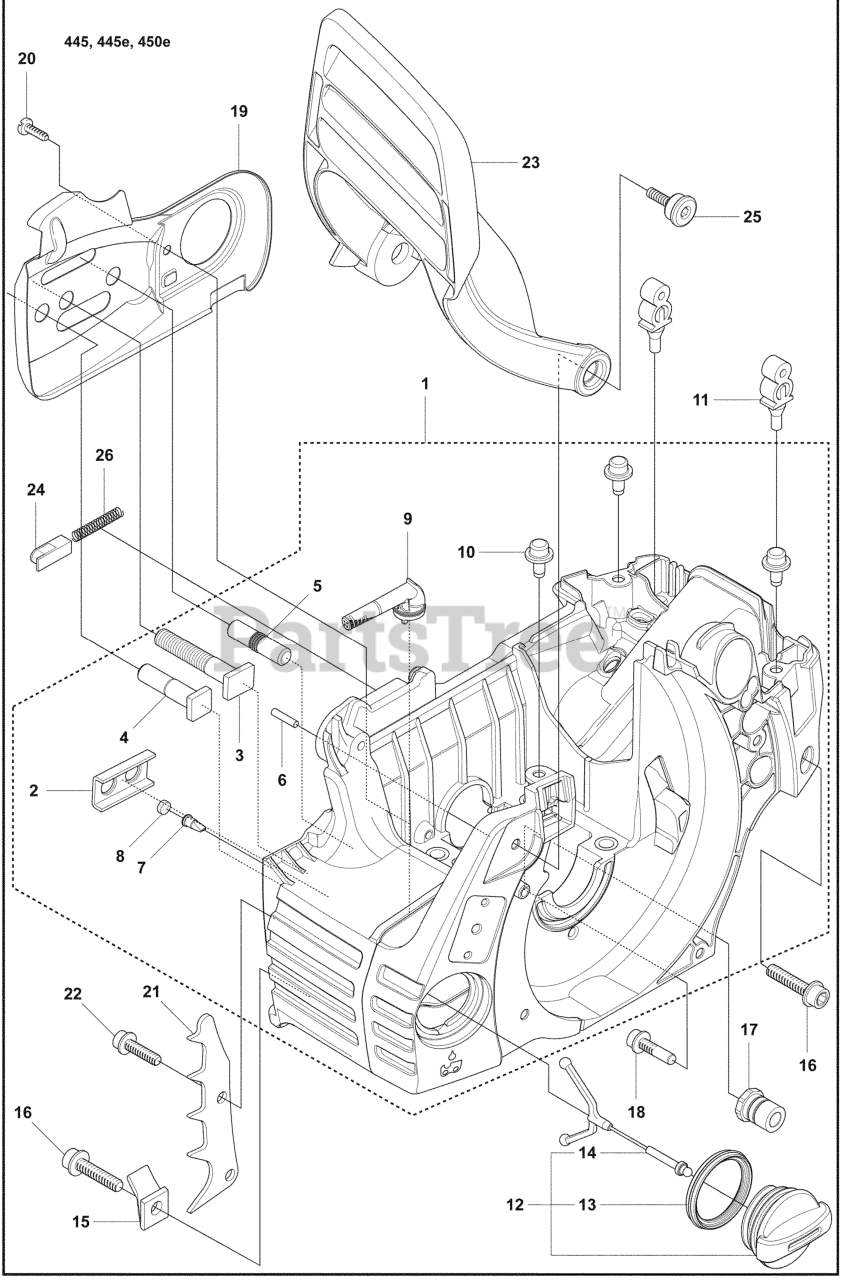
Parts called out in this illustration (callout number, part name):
2	STIFFENING PLATE
7	VALVE-CHECK (DUCKBILL)
8	PLUG
9	OIL SCREEN
11	SUPPORT
12	TANK CAP ASSY
13	SEALING
15	CHAIN CATCHER
16	SCREW IHSCFT
17	LATERAL SUPPORT
18	SCREW IHSCFT
19	CHAIN GUIDE PLATE
23	HAND GUARD
25	SCREW
26	LOCK SPRING
